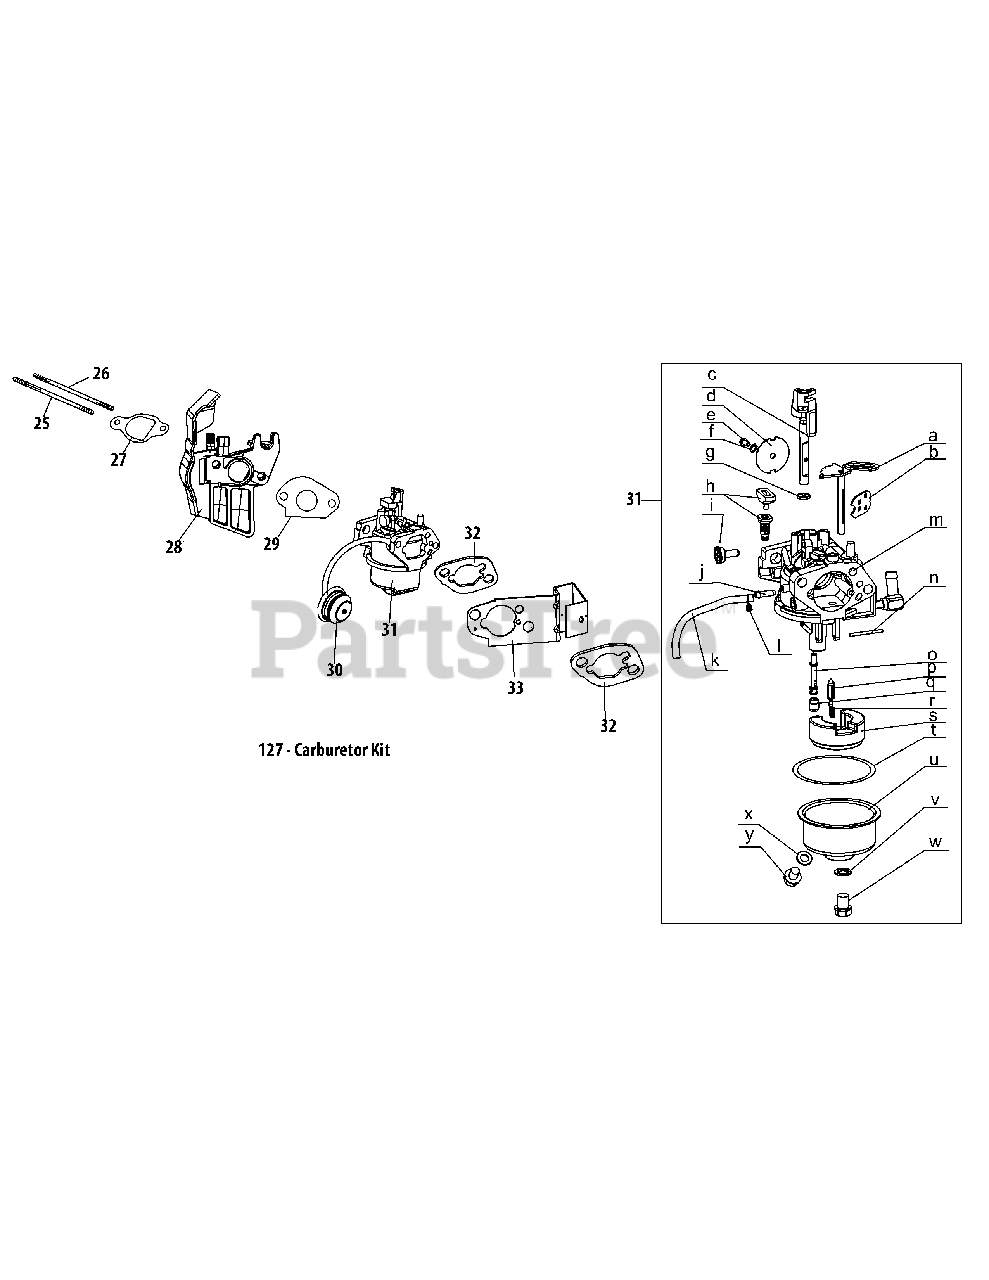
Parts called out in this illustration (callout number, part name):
25	Stud M6×117
26	Stud M6×105
27	Carburetor Insulator Gasket
28	Carburetor Insulator
29	Carburetor Gasket
30	Primer Bulb
31	Carburetor Assembly
32	Carburetor Gasket Plate
33	Choke Control Bracket
127	Carburetor Kit
